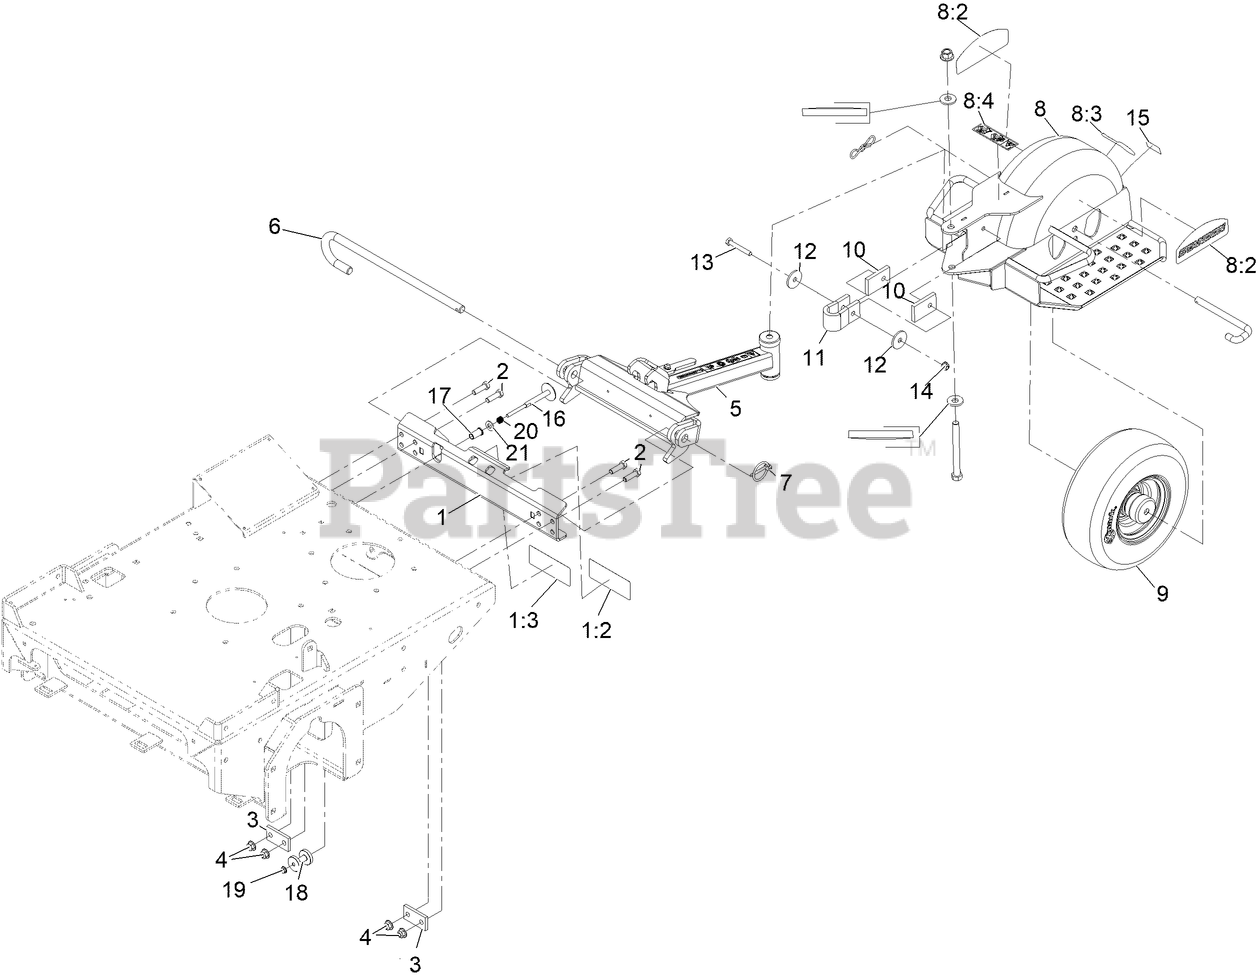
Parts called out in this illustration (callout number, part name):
1	MOUNT PLATE W/ DECALS ASM
1:2	DECAL-BELT DRIVE WARNING
1:3	DECAL-WARNING, SULKY
2	SCREW-HH
3	PLATE,BACK-UP (PLATED)
4	NUT-HF, NI
5	ASM, DRAW BAR
6	PIN, PIVOT
7	PIN-LYNCH
8	ASM-SULKY FRAME W/ DECALS
8:2	DECAL, STANDON
8:3	DECAL, EXMARK
8:4	DECAL-WARNING HAND PINCH
9	ASM, WHEEL AND BEARINGS
10	PAD,STOP
11	STOP, ROTATION
13	SCREW-HH
14	NUT-HF, NI
15	Decal-Patent Ttco.Com
16	PLUNGER-SULKY ASM
17	BUSHING-PLASTIC
18	TARGET-SWITCH
20	Spring,Compression
21	WASHER-FLAT
